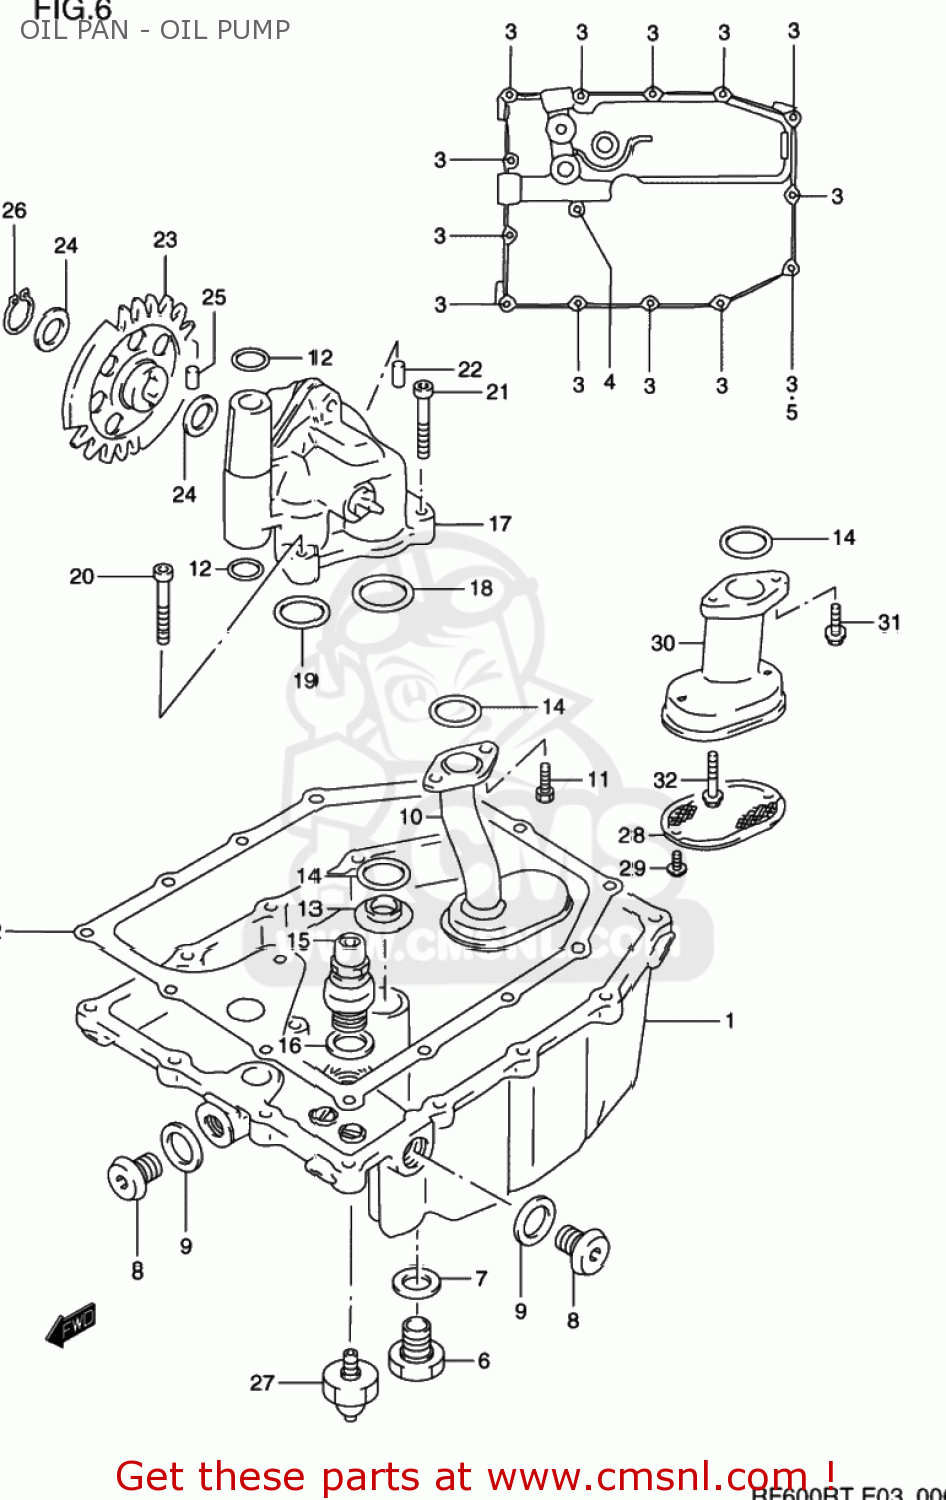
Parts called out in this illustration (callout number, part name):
1	PAN,OIL
2	GASKET,OIL PAN
3	SCREW
4	BOLT
5	GASKET(5.8X11X1.2) (NAS)
6	PLUG
7	GASKET(13.8X18.8X4.8) (NAS)
8	PLUG
9	GASKET(16X22X2) (NAS)
10	STRAINER COMP,ENGINE OIL
11	SCREW
12	O RING(D:2.4,ID:11.8)
13	GASKET,OIL OUTLET (NAS)
14	O RING(D:3.2,ID:17.8)
15	VALVE ASSEMBLY,OIL RELIEF
16	GASKET(16X22X2) (NAS)
17	PUMP ASSY,ENGINE OIL
18	O RING(D:2.4,ID:26.2)
19	O RING(D:3.2,ID:17.8)
20	BOLT
21	BOLT
22	PIN
23	GEAR,OIL PUMP DRIVEN(NT:37)
24	SHIM
25	PIN(5X18)
26	CIRCLIP,12 MM
27	SWITCH ASSEMBLY,OIL PRESSURE
28	STRAINER,ENGINE OIL
29	BOLT
30	PROTECTOR,OIL STRAINER
31	BOLT
32	BOLT, HYDRAULIC UNIT NO.2
